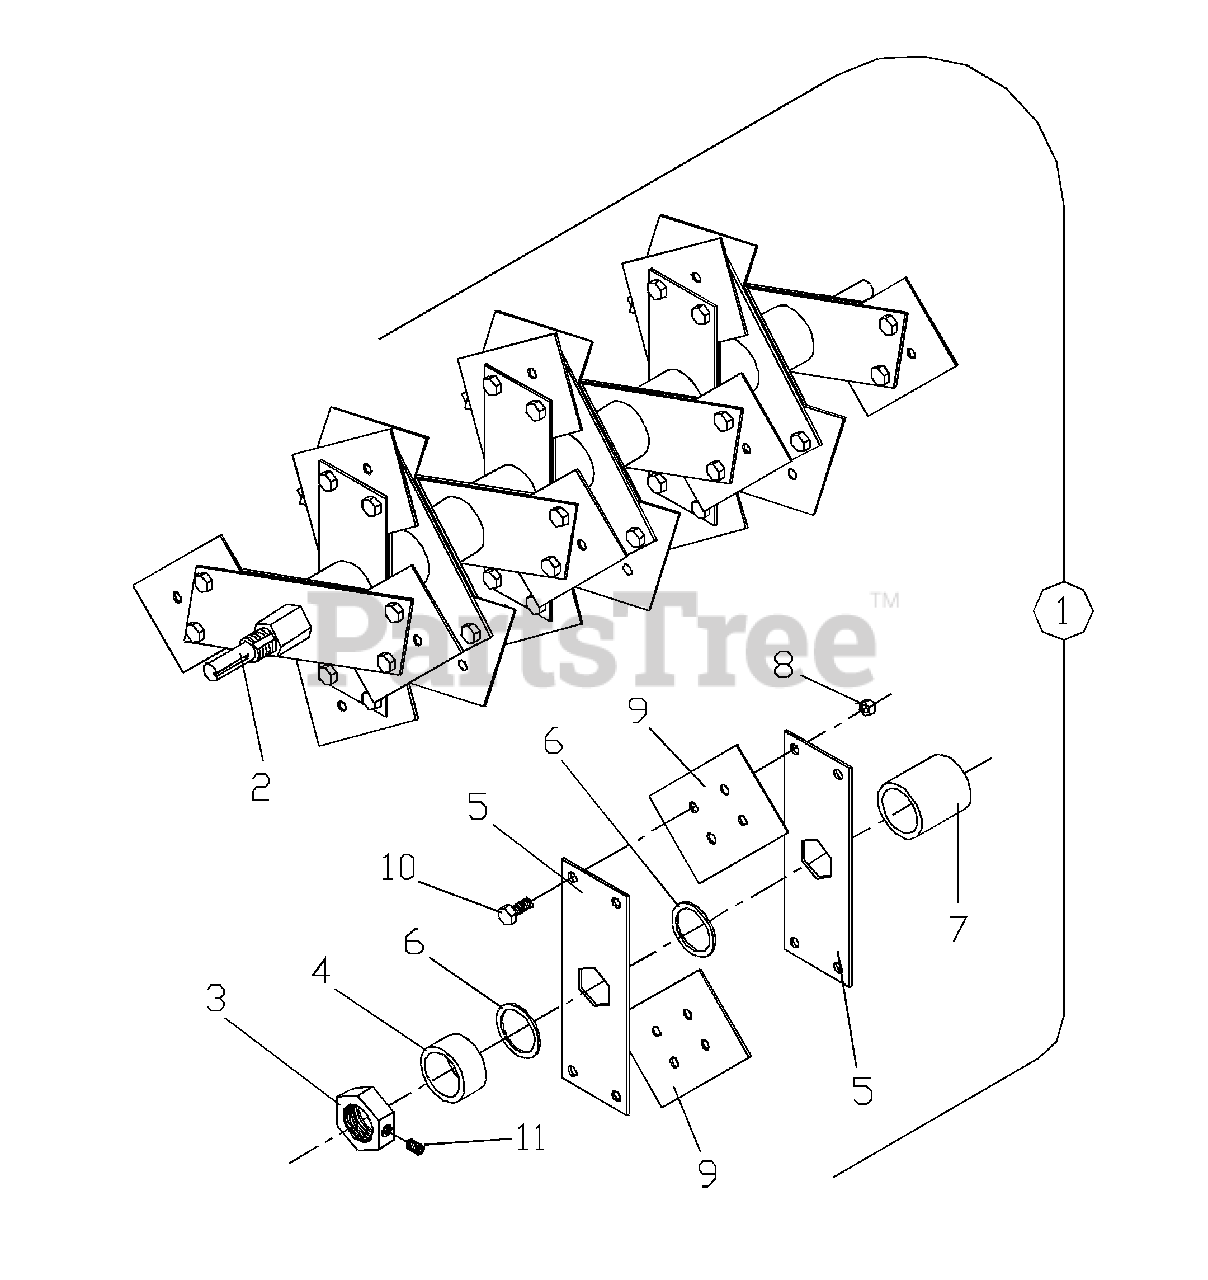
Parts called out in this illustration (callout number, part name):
1	SLICER SHAFT, COMPLETE
2	SLICER SHAFT
3	JAM NUT W/SET SCREW
4	SLEEVE SPACER, SHORT
5	BLADE HOLDER PLATE
6	BLADE WASHER
7	SLEEVE SPACER, LONG
8	1/4-20 NYLOC NUT
9	SLICER BLADE
10	1/4-20 X 5/8 HCS
11	5/16-18 X 3/8 SET SCREW
